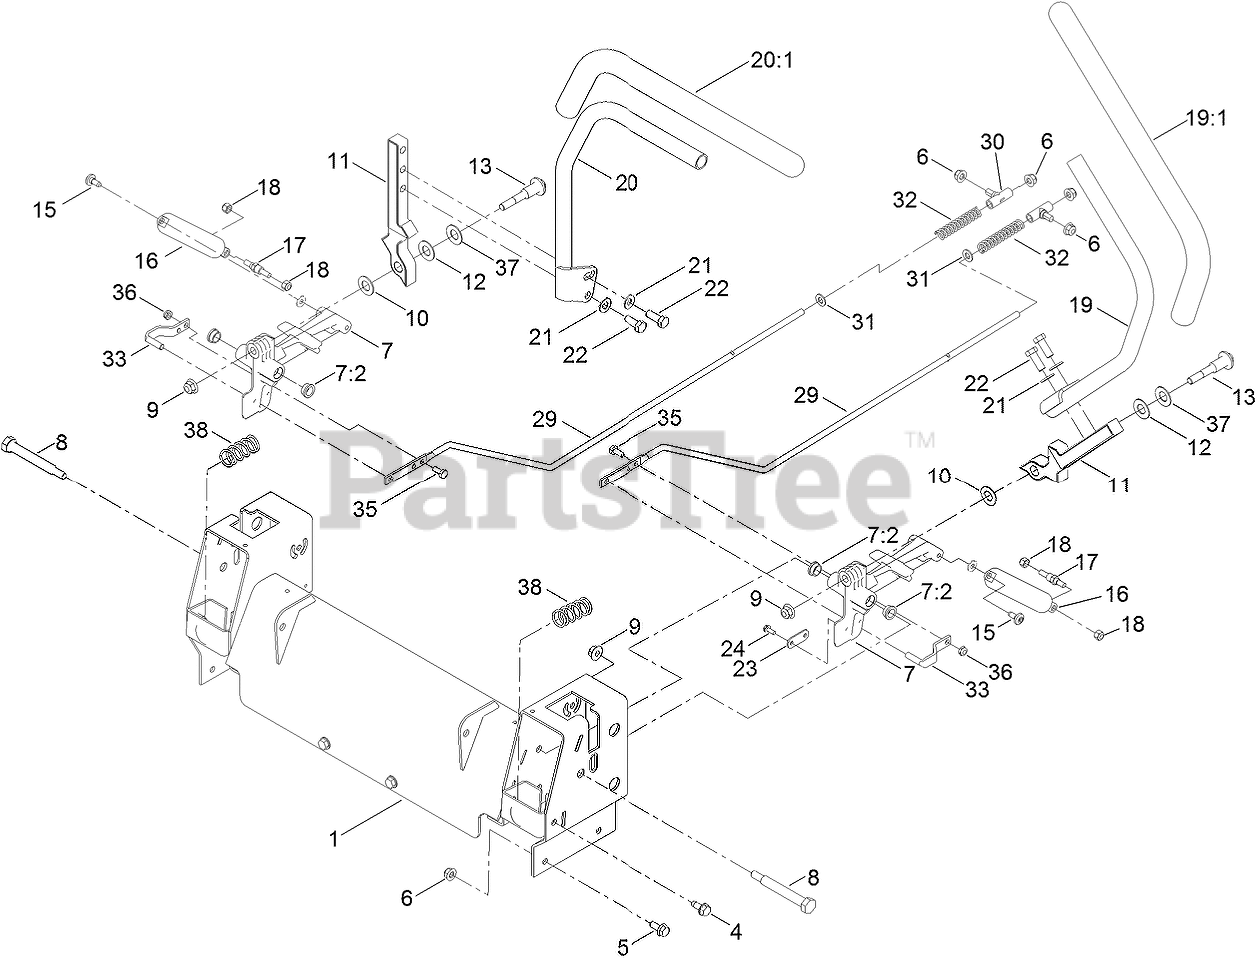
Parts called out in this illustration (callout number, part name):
1	CONTROL BOX ASM
4	SCREW-HWHTF
5	SCREW-HHF
6	NUT-HF
7	ACTUATOR ARM ASM
7:2	BUSHING-FLANGE
8	BOLT-PIVOT
9	NUT-HF, NI
10	WASHER-NYLON
11	ARM-CONTROL
12	WASHER
13	BOLT-PIVOT
15	SCREW-SHOULDER
16	DAMPER-NON CAVITATING
17	STUD-DAMPER
18	NUT-HEX
19	HANDLE-CONTROL, LH
20	HANDLE-CONTROL, RH
21	WASHER-FLAT
22	SCREW-HH
23	PLATE-STOP,HYDRO
24	SCREW-TAPTITE
29	ROD-HYDRO
30	MOUNT-ROD, HYDRO
31	WASHER-PLAIN
32	SPRING-COMPRESSION
33	PIN-ROD, HYDRO
35	SCREW-HH
36	NUT-HEX
37	WASHER-BELLEVILLE
38	SPRING-RETURN
